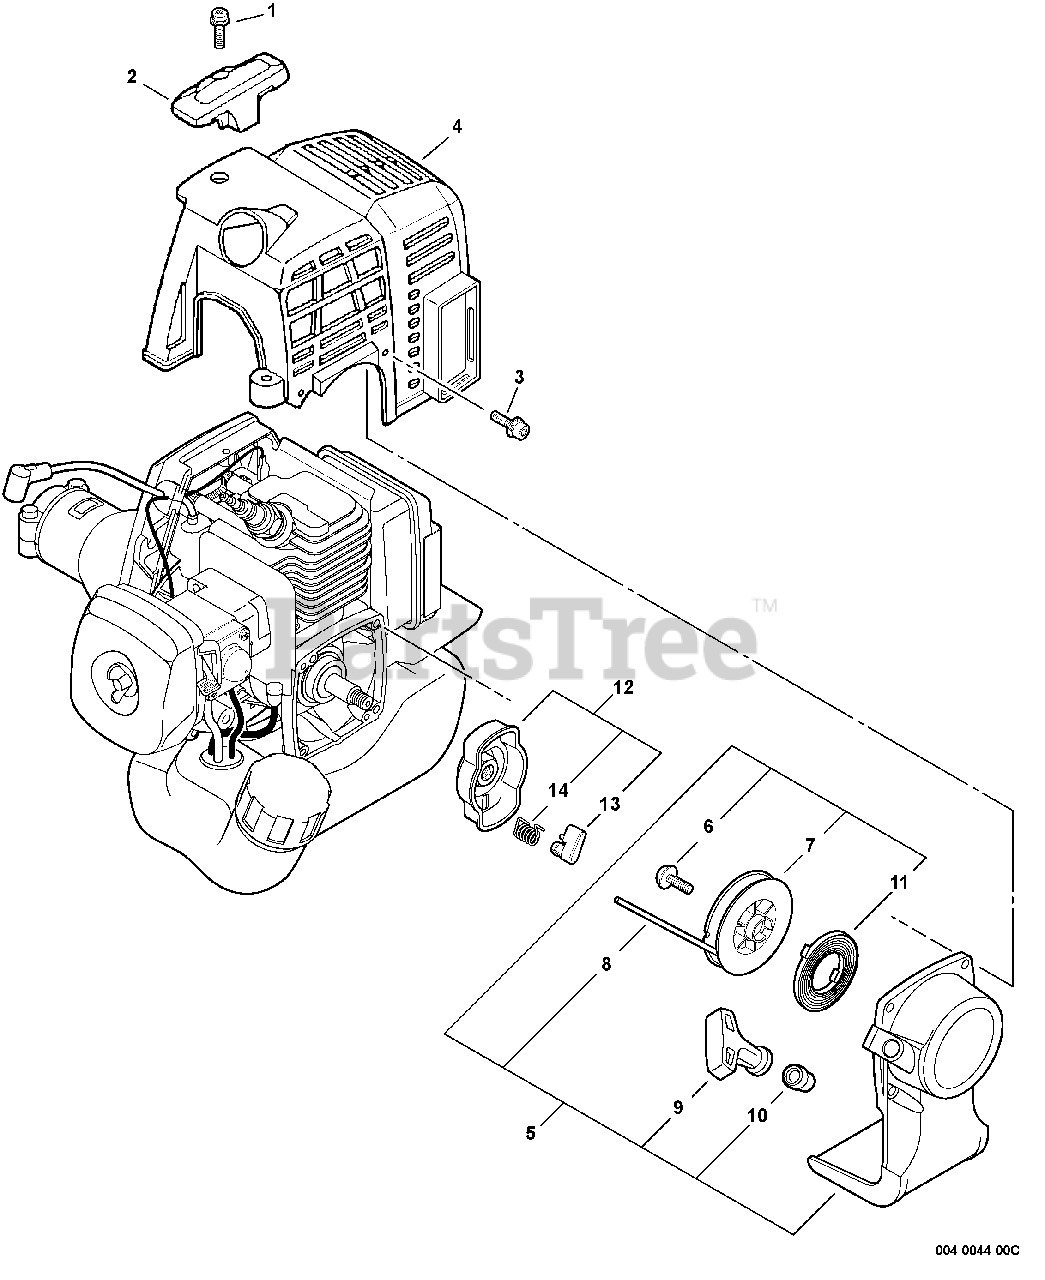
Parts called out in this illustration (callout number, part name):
1	SCREW - 5X16
2	GUARD - TOP
3	SCREW - 4X16
4	COVER, ENGINE
5	STARTER ASSY
7	REEL, ROPE
8	ROPE, STARTER - 3X1000
9	GRIP, STARTER
10	GUIDE, ROPE
11	SPRING, REWIND
12	STARTER PAWL ASSY
13	PAWL, STARTER - BLACK
14	SPRING, RETURN
